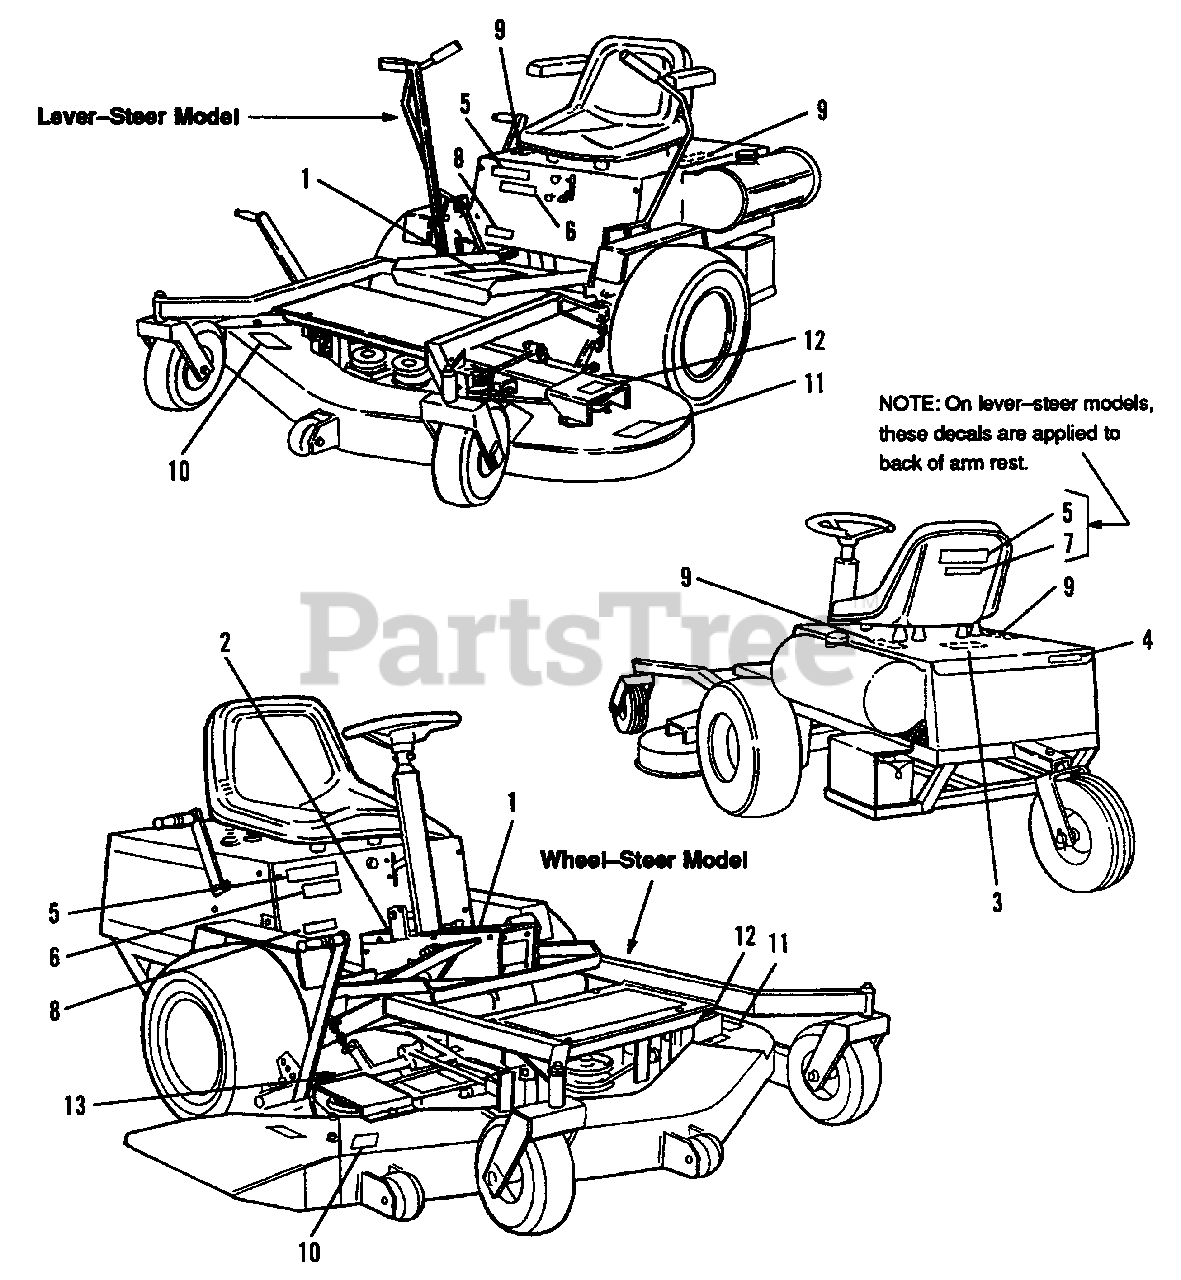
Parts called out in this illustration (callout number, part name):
1	DECAL, Caution and Controls (Wheel-Steer Models)
1	DECAL, Caution and Controls (Lever-Steer Models)
2	DECAL, Starting Instructions (Wheel-Steer Models)
3	DECAL, Hot (Located under seat deck)
4	DECAL, Rear Frame (16 HP)
4	DECAL, Rear Frame (18 HP)
4	DECAL, Rear Frame (20 HP)
5	DECAL, Simplicity
6	DECAL, Professional (Black)
7	DECAL, Professional (Orange)
8	I.D. PLATE
9	DECAL, Tow Control (Located on Hydro Pump tow latches)
10	DECAL, Danger
11	DECAL, Danger
12	DECAL, Width 46" (1691847)
12	DECAL, Width 54" (1691848)
12	DECAL, Width 60" (1691849)
12	DECAL, Width 66" (1691850)
13	I.D. PLATE
